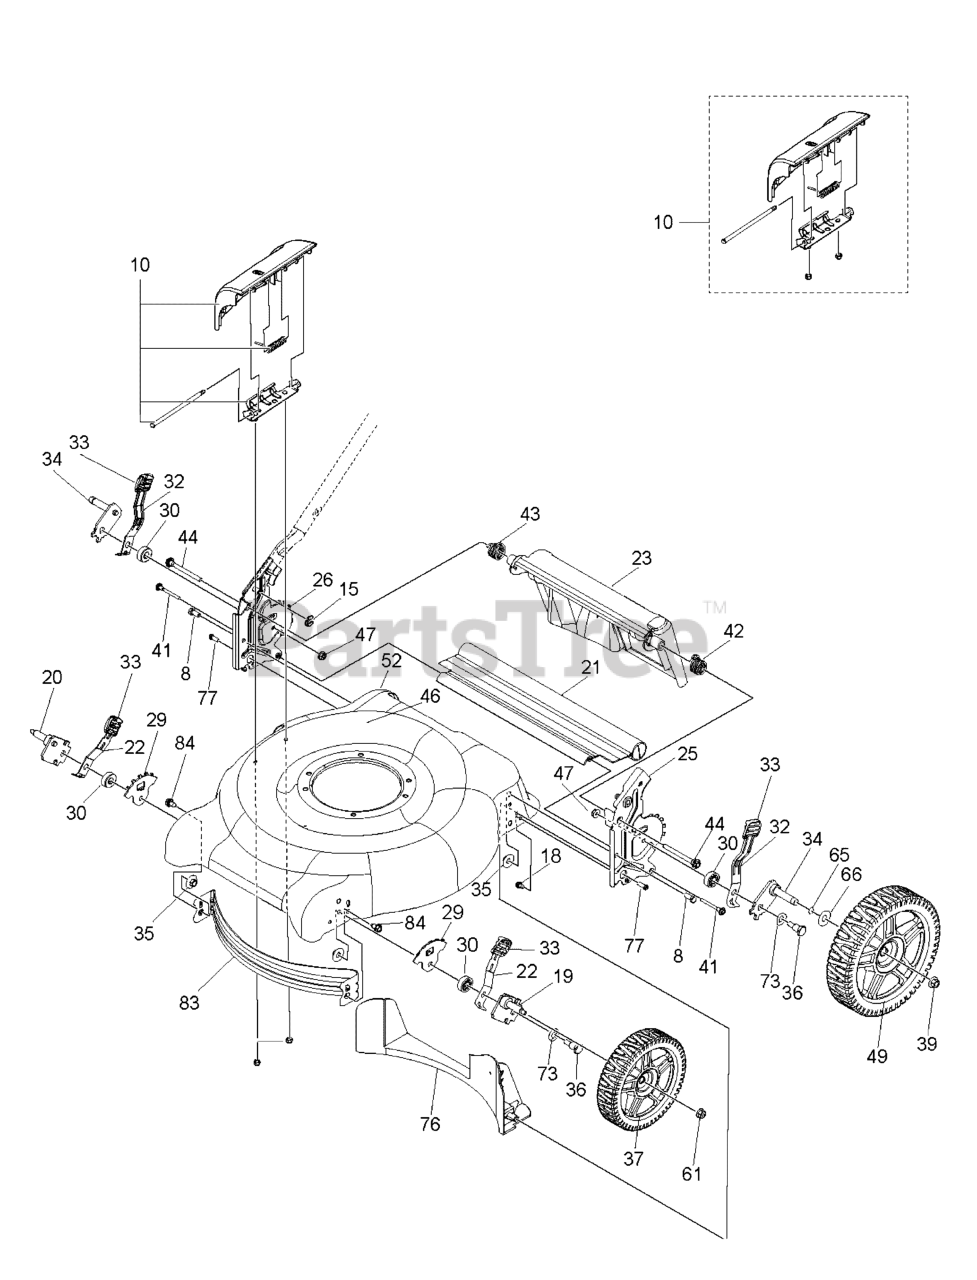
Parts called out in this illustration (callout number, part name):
8	Screw Thdrol 5/16-18 x 3/4
10	DISCHARGE CHUTE
15	CLIP, Retainer
18	Screw Hex Washead 1/4-20 X 3/8
19	AXLE, Front, Left
20	AXLE, Front, Right
21	COVER, Dust
22	SPRING
23	DEFLECTOR, Rear
25	BRACKET, Left
26	BRACKET, Right
29	BRACKET, Height
32	Selector Spring, Rear
33	Selector Knob
34	AXLE, Rear
35	NUT, Hex, Flangelock 5/16-18
36	BOLT, Shoulder, 5/16-18 x .33
37	Wheel & Tire Assembly, Rear
39	NUT, Lock Flange, 3/8-16 UNC
41	Screw, Hinge
42	Spring, Rear Door, LH
43	Spring, Rear Door, RH
44	Bolt, Rear Skirt
46	Decal Deflect WRN. Cutfinger
49	WHEEL
52	KIT, Housing
61	NUT, Hex, Flangelock 3/8-16
66	WASHER, Flat, 3/8
73	Washer, Curved, Cylindrical
76	BAFFLE, Rear
77	Screw, Hex Washer Head, #13 x 3/4
83	Baffl e, Front
84	SCREW, 5/16-18
